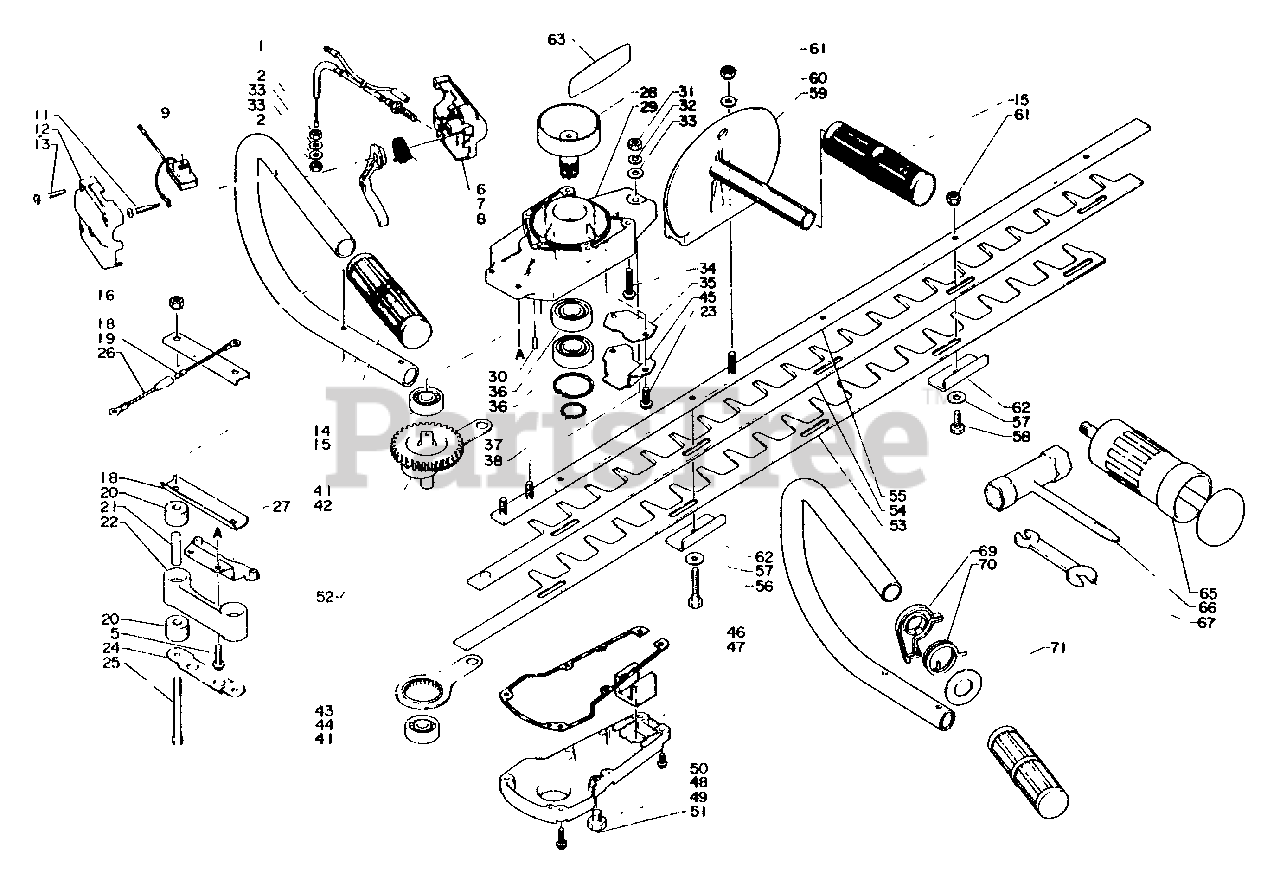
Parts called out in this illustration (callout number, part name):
1	CABLE, THROTTLE
5	SCREW 5×16
6	BRACKET, THROTTLE CONTROL - RIGHT
7	SPRING, THROTTLE RETURN
8	TRIGGER, THROTTLE
9	IGNITION SWITCH ASSY
11	SCREW 4×30
12	BRACKET, THROTTLE CONTROL - LEFT
13	SCREW 4×25
14	HANDLE - REAR
16	LOCKNUT - 5
19	LEAD - GROUND
21	SPACER
22	BRACKET, HANDLE
23	BOLT 5×14
25	BOLT 5×60
26	LEAD - GROUND
28	DRUM, CLUTCH
29	CASE, GEAR
30	PIN, LOCATING 4
31	NUT, HEX M6
32	WASHER, SPRING 6
33	WASHER 6.5×11.5×0.8
34	SCREW 5×30
35	GUIDE
36	BEARING, BALL 6003
37	RING, SNAP 35
38	RING, RETAINING - 16
41	BEARING, BALL 6200
42	GEAR
43	BEARING, NEEDLE
44	CONNECTING ROD ASSY
45	GUIDE
46	GASKET, GEAR CASE
48	LID, GEAR CASE
49	BOLT 8×8 SP
50	SCREW 4×14
51	SCREW 4×22
52	GEAR ASSY
53	TRIMMER BLADE SET
54	TRIMMER BLADE SET
55	BAR, FRAME
56	BOLT 6×40
58	BOLT 6×22
59	HANDLE, FRONT
61	LOCKNUT - 6
62	INSULATOR
63	LABEL - ECHO
65	PUMP, GREASE
66	WRENCH 14×19 W/S.DRIVER
67	SPANNER 8×10
69	LOCKOUT, TRIGGER
70	SPRING, THROTTLE LOCKOUT
71	SPACER
